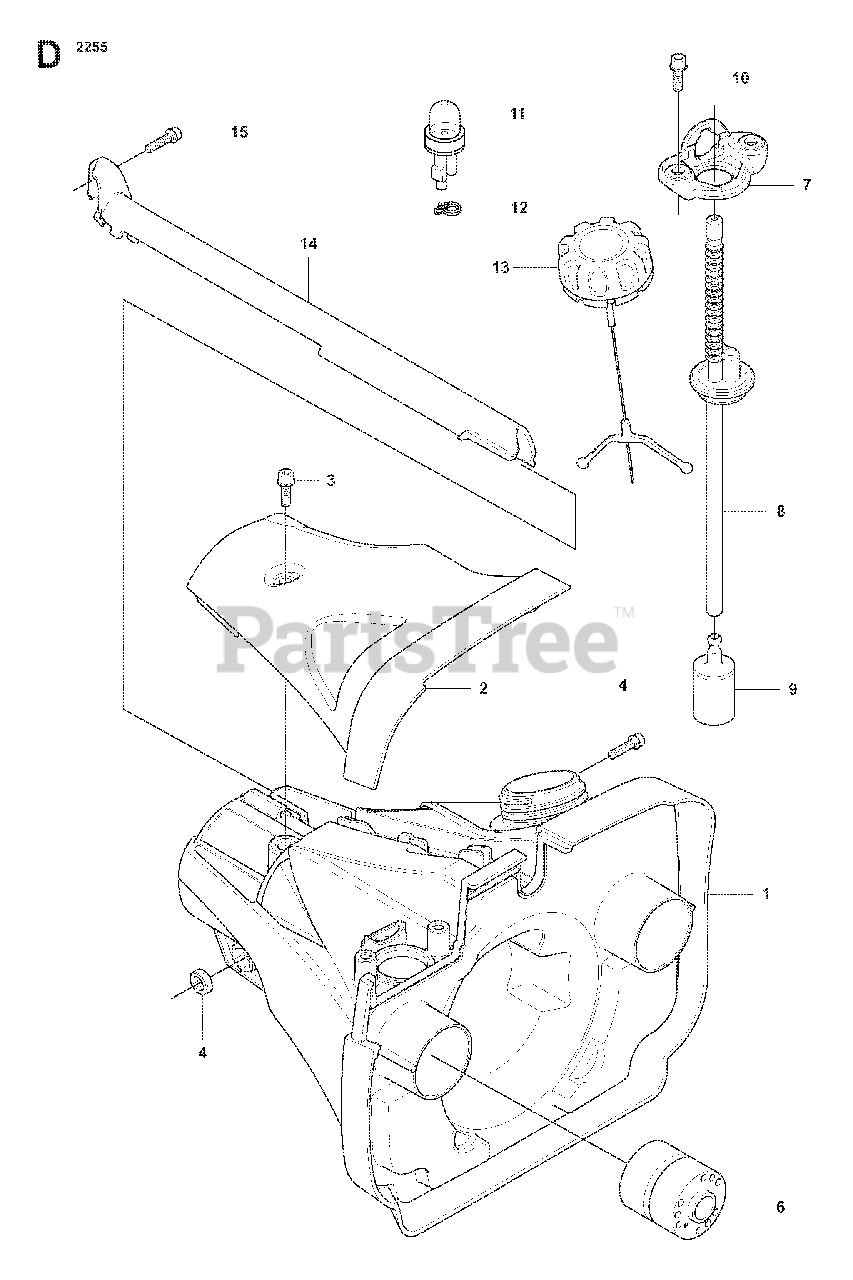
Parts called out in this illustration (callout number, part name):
3	SCREW IHSCFM
6	ANTIVIBE ELEMENT
8	FUEL HOSE
9	FUEL FILTER
11	AIR PURGE BUBBLE
12	HOSE CLAMP
15	SCREW IHSCFM
